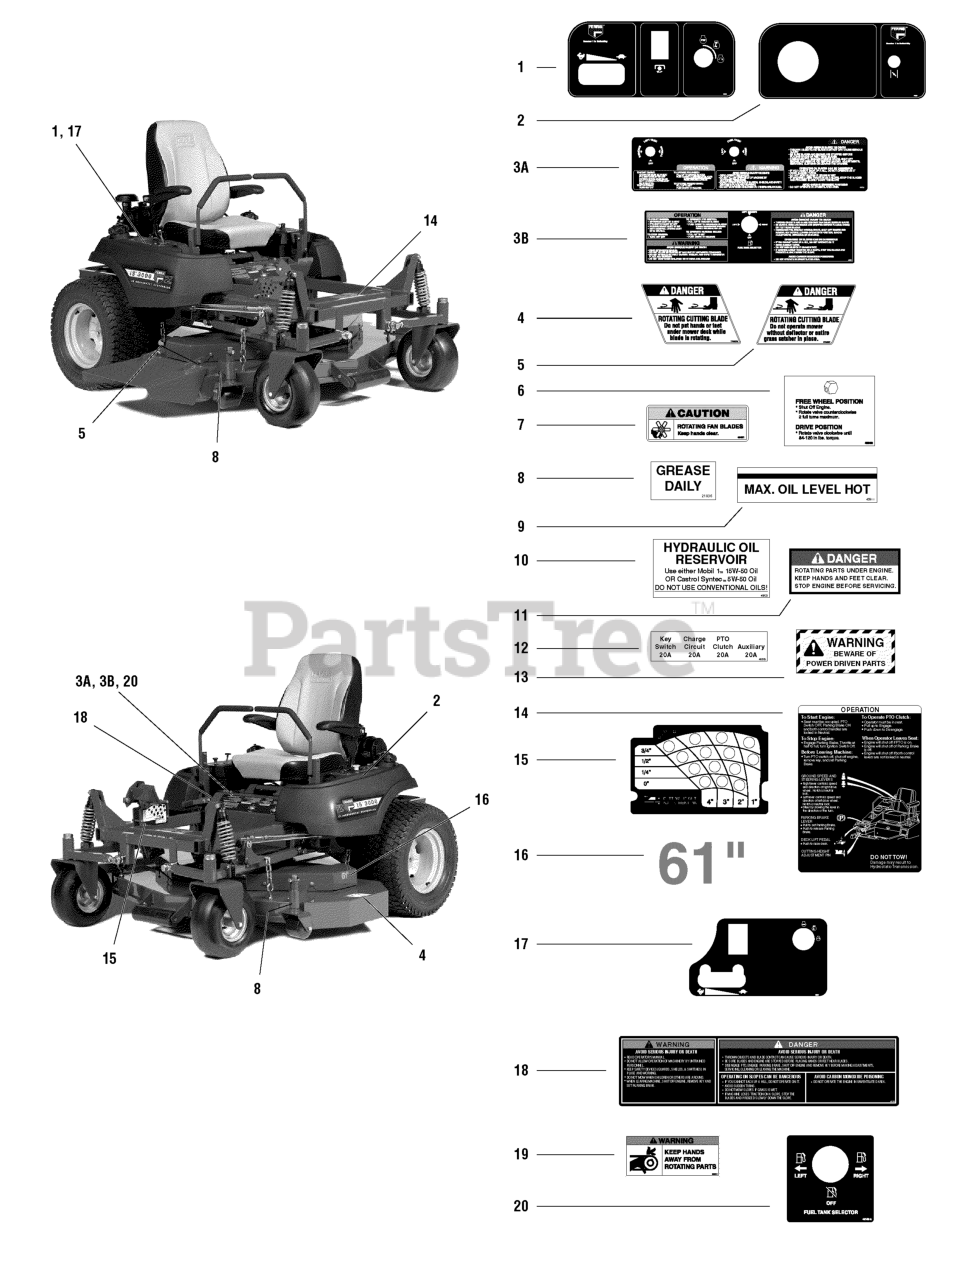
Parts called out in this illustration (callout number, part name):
1	DECAL, Control Panel-RH
2	DECAL, Control Panel-LH
3A	DECAL, Safety/Instruction
3B	DECAL, Safety/Instruction
4	DECAL, Danger (Hand Under Deck)
5	DECAL, Danger (Chute In Place)
6	DECAL, Hydro Release Valve
7	DECAL, Caution Fan
8	DECAL, Grease Daily
9	DECAL, Max. Oil Level
10	DECAL, Oil Reservoir
11	DECAL, Danger, Rotating
12	DECAL, Fuse Location
13	DECAL, Warning
14	DECAL, Operation
15	DECAL, Deck Height
16	DECAL, 61"
17	DECAL, Control Panel
18	DECAL, Safety/Instruction
19	DECAL, Warning
20	DECAL, Fuel Selector
